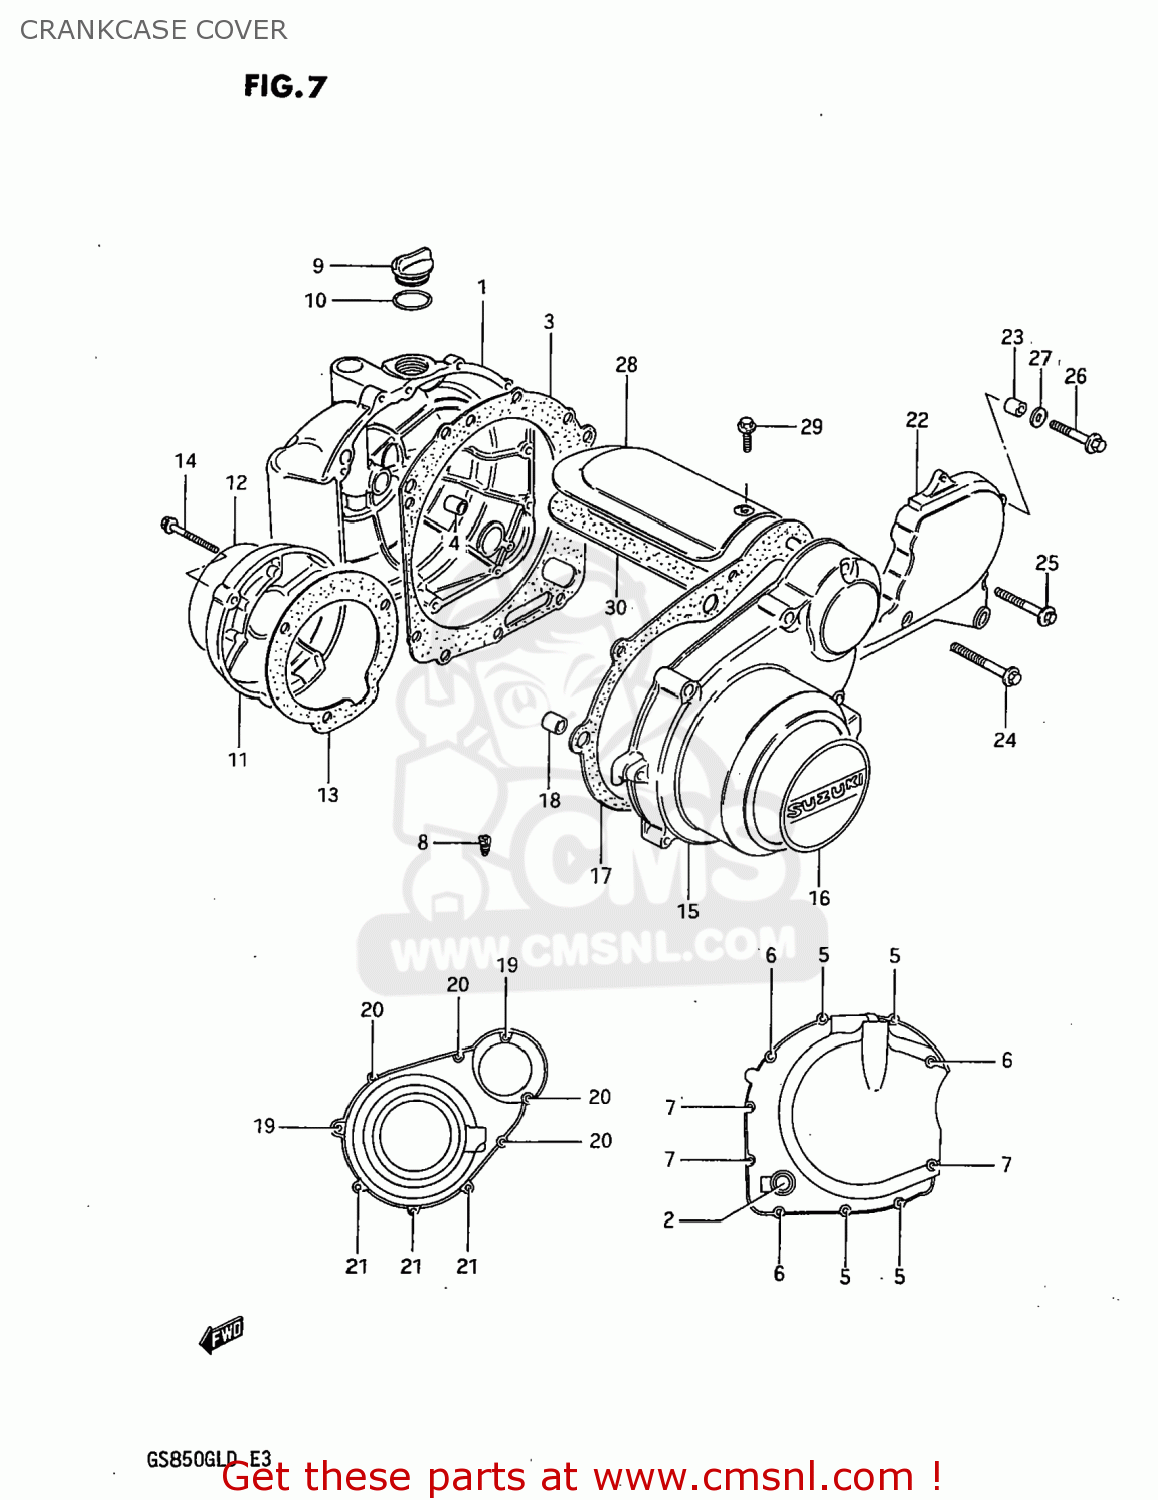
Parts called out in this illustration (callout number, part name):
1	COVER,CLUTCH
2	LENS,OIL LEVEL CHECK
3	GASKET,MAGNETO COVER (N (MCA)
4	PIN
5	BOLT
6	BOLT (6X30)
7	BOLT (6X35)
8	JET
9	CAP
10	O RING(D:2.2,ID:32)
11	COVER,CONTACT BREAKER
12	EMBLEM,CONTACT BREAKER COVER
13	GASKET,CONTACT BREAKER COVER (NAS)
14	BOLT (5*30)
15	COVER,MAGNETO
16	EMBLEM,MAGNETO COVER
17	GASKET,MAGNETO COVER (MCA)
18	PIN
19	BOLT
20	BOLT (6X40)
21	BOLT (6X35)
22	COVER,SPROCKET
23	PIN
24	BOLT (6X30)
25	BOLT (6X20)
26	BOLT
27	WASHER
28	COVER,STARTER MOTOR
29	BOLT
30	GASKET,STARTER MOTOR COVER (MCA)
